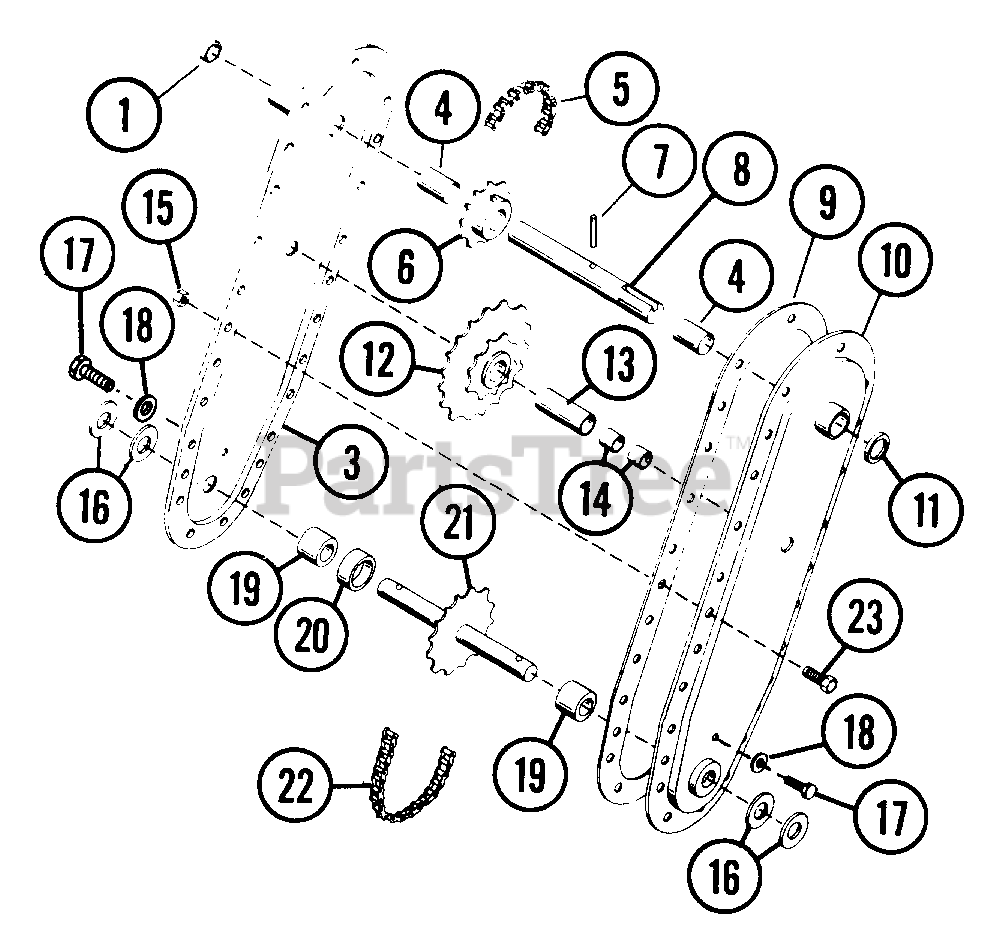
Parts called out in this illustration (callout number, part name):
1	EXPANSION PLUG CONCAVE STD 13/
3	RH CHAIN
4	BSHG-SLV .625X.812X2.000 SB
5	CHAIN #35
6	SPROCKET
7	PIN-GRV .250X1.25 TP E
8	INPUT SHAFT
10	L H CHAIN
11	SEAL .625X.816X.125
12	SPROCKET
13	BRG-RACE .321X.562X1.53
14	BRG-NEEDLE .562X.750X.750
15	NUT-KEPS .250-20
16	SEAL 1.250X1.696X.218
17	SCR-TAP .250-20X.37 SLPH PL C
18	GASKET,
19	BRG-NEEDLE 1.25X1.50X1.0
20	SPACER 2.50 X 1.26 X .48
21	TINE SHAFT
22	CHAIN #50
23	SCR-SEMS .25-20X.62 PL
